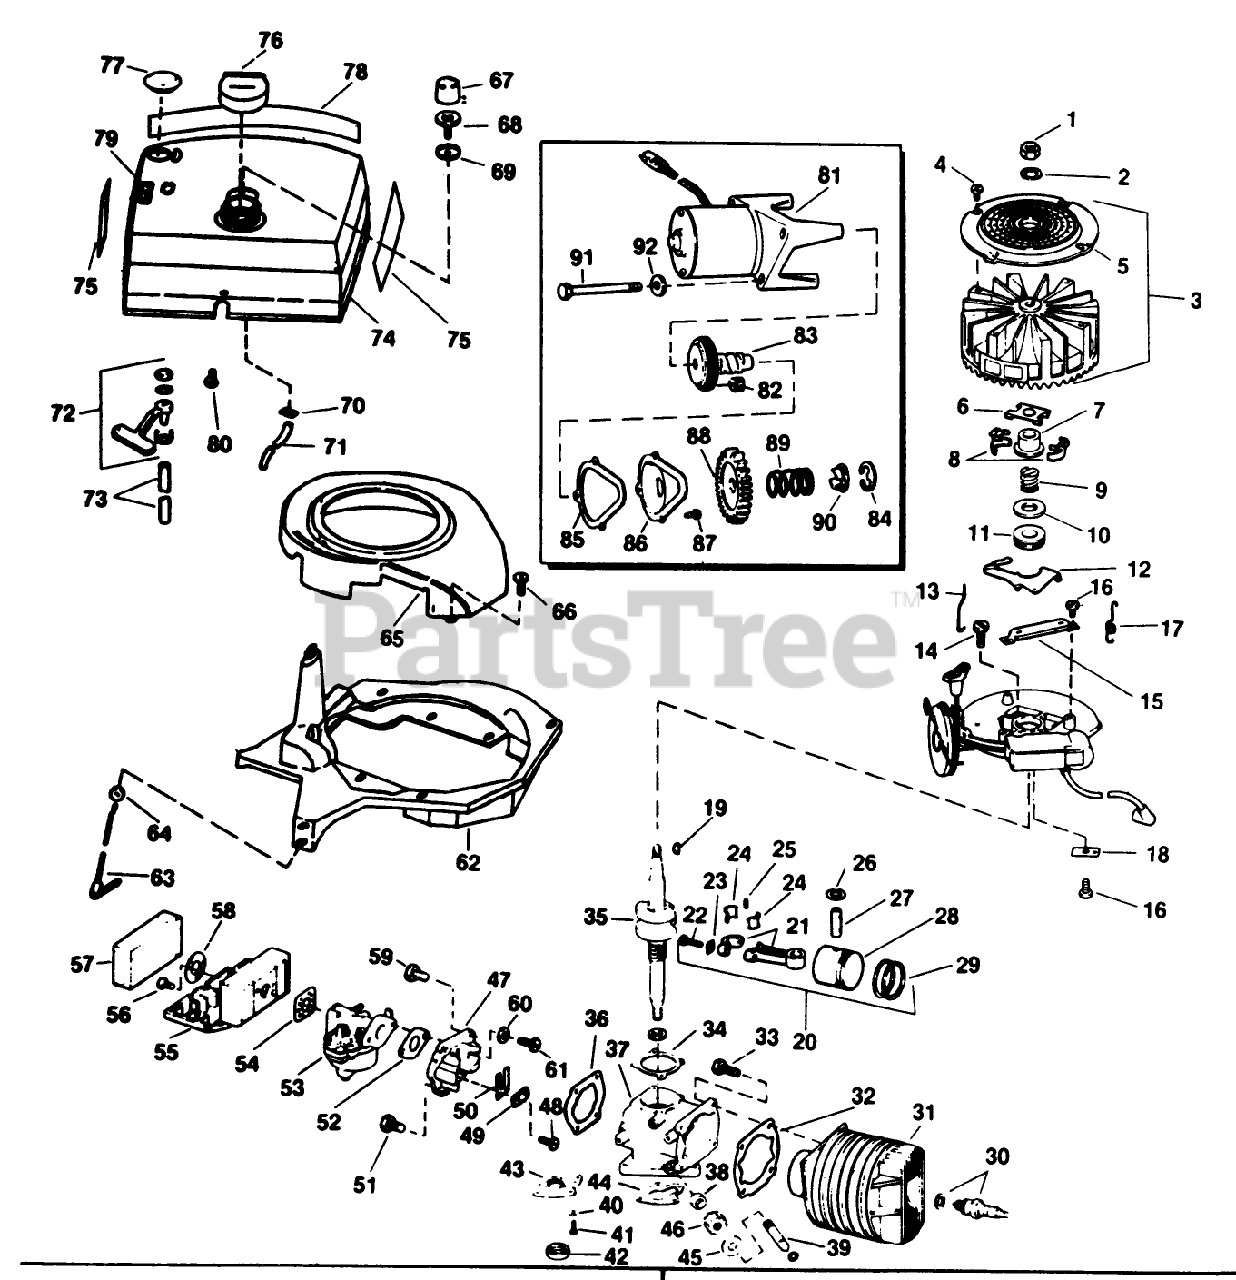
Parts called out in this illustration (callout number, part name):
4	SCREW F
7	COLLAR S
9	SPRING S
12	LEVER-GOVERNOR S
14	SCREW S
15	BRACKET
16	SCREW S
24	LINER ASM
26	RING-RETAINING
30	Spark Plug
32	GASKET S
34	GASKET S
36	GASKET S
43	GEAR COVER S
44	GASKET-CVR S
45	THRUST WASHER
46	GEAR, DR SHAFT S
47	REED PLATE AY. S
49	PLATE-BACKUP, REED
51	SCREW S
52	GASKET S
54	GASKET S
56	SCREW S
57	AIR FILTER S
58	WASHER S
59	SCREW S
64	GROMMET
69	CUP-BULB
70	LOCKNUT S
80	SCREW S
84	Retainer
